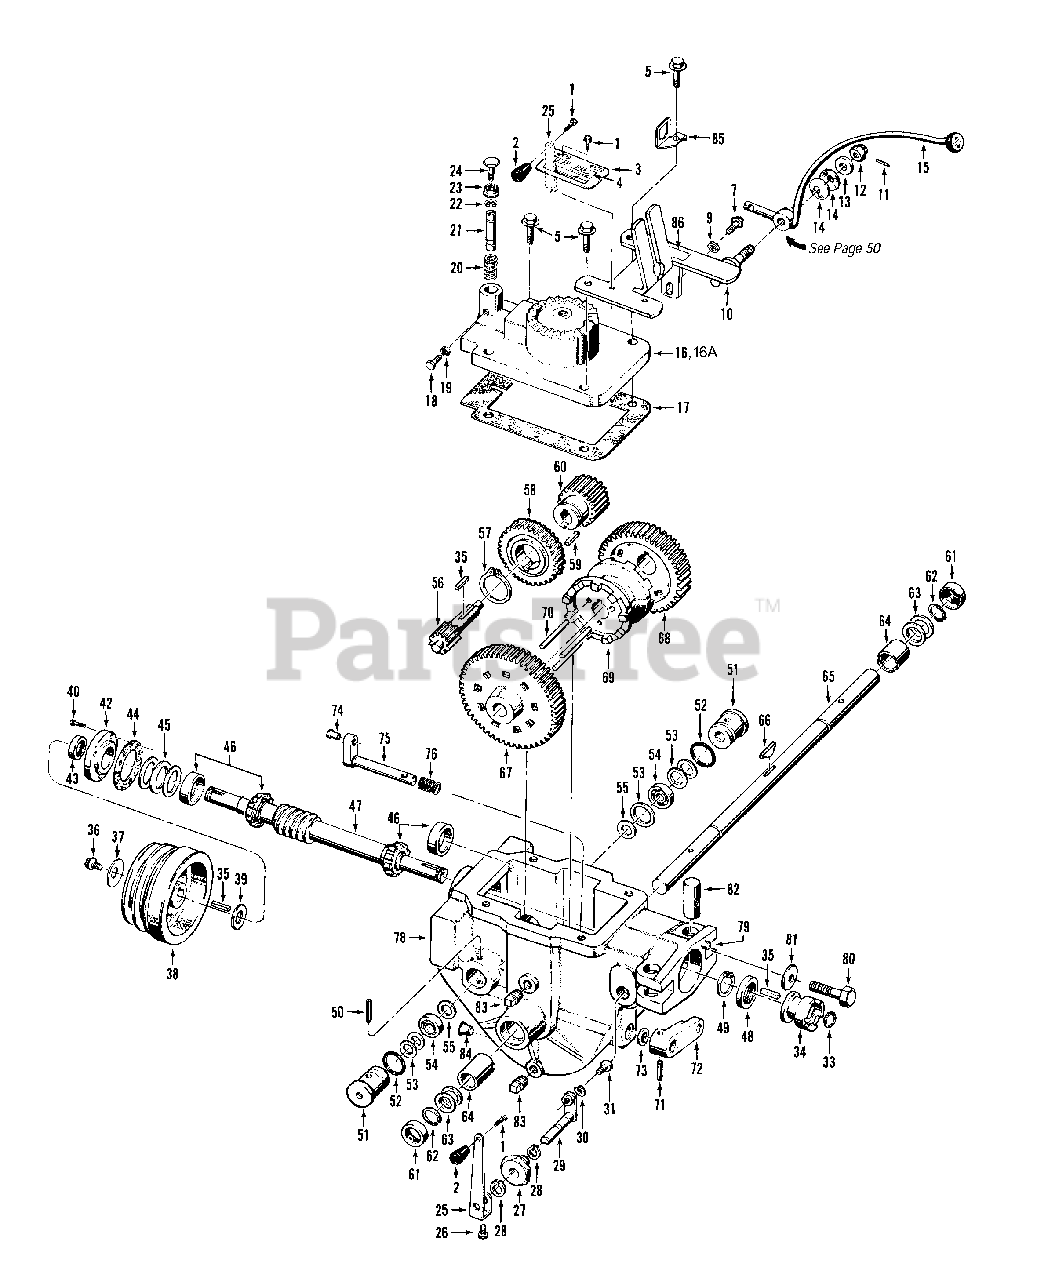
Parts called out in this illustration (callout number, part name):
1	Bolt-hex hd., #10-32 x 3/8", self-locking flange
2	Knob-tines/PTO clutch lever, tapered, plastic
3	Detent Plate-tines/PTO clutch lever
4	Decal-operating instructions, detent plate
5	Bolt-flanged hex hd., 3/8-16 x 1-1/2"
7	Bolt-flanged hex hd., 5/16-18 x 3/4", Grade 5
9	Washer-flat, 5/16", S.A.E.
10	Bracket-shift levers
11	Pin-spring, 1/8"
12	Nut-castle (slotted), 1/2"-20,
13	Washer-shoulder, 1/2"
14	Washer-disc spring
15	Lever-wheel speed shift
16	Cover-power unit transmission
16A	Cover-power unit transmission
17	Gasket-transmission cover
18	Bolt-hex hd., 5/16-18 x 1", Grade 5,
19	Nut-hex, 5/16"-18
20	Spring-neutral plunger
21	Plunger-neutral
22	Clip Ring-retains neutral plunger
23	Nut-hex, flange locknut, 3/8"-16
24	Bolt-hex hd., 3/8-16x1-1/2", threaded full length
25	Lever-eccentric, tines/PTO clutch.
26	Bolt-hex hd., 1/4-20 x 1/2"
27	Bushing-tines/PTO clutch lever eccentric shaft
28	Retaining Ring-(snap ring), external
29	Eccentric-shaft, tines/PTO clutch lever
30	Lockwasher-hi-collar, 1/4"
31	Screw-socket hd., 1/4-20 x 3/8"
33	Retaining Ring-external
34	Dog Clutch-power unit
35	Key-3/16 sq. x 1"
36	Bolt-hex hd., 5/16-24 x 3/4", self-locking flange, Grade 5
37	Washer-disc spring (concave)
38	Pulley-transmission drive, cast iron
39	Washer-flat, hardened shoulder 1-1/4"
40	Bolt-hex hd., 1/4-20 x 3/4", front bearing cap
42	Cap-front bearing
43	Seal-oil, front bearing cap
44	Gasket-front bearing cap
45	Shim-front bearing cap, .010" thick
45	Shim-as above, .030"
45	Shim-as above, .005"
45	Shim-as above, .062"
46	Bearing & Cup-tapered cone roller bearing with cup (race).
47	Shaft-main drive, power unit.
48	Seal-oil, drive shaft, rear
49	Retaining Ring-(snap ring), internal
50	Pin-roll (spirol), 1/4 x 2"
51	Plug-retaining, pinion bearing
52	O-Ring-retaining plug
53	Shim-retaining plug, 1-1/64" inner dia., .033" thick
53	Shim-same as 1132-1, .062"
53	Shim-same as 1132-1, .010"
54	Bearing-ball, pinion shaft
55	Washer-pinion shaft
56	Stem Pinion-slow speed gear & shaft
57	Ring-retaining, external
58	Worm Gear-bronze, wheel drive
59	Key-3/16" x 5/8"
60	Gear-fast speed pinion
61	Seal-oil, wheel shaft
62	Retaining ring-external
63	Shim-wheel shaft, 1-1/64" inner dia., .062" thick
63	Shim-as above, .030" thick
63	Shim-as above, .015" thick
63	Shim-as above, .010" thick
63	Shim-same as above, .005" thick
64	Bushing-bronze, wheel shaft bearing
65	Shaft-wheel, 15-5/8",
66	Key-Hi Pro, 1/4" x 1-3/4"
67	Gear-slow speed, wheel drive
68	Gear-fast speed, wheel drive
69	Dog Clutch-wheel drive
70	Pin-clutch guide, 1/4" diameter
71	Pin-roll, 3/16" x 1-1/4" (spirol)
72	Lever-eccentric, wheel speed shifting
73	Seal-oil, eccentric shaft
74	Pin-eccentric shaft, wheel speed shifting
75	Eccentric Shaft-wheel speed shifting
76	Spring-eccentric shaft
78	Housing-power unit transmission
79	Pin-alignment
80	Bolt-hex hd., 1/2-13 x 2" Grade 5
81	Washer-disc spring (concave),
82	Post-with threaded hole
83	Plug-pipe, 1/4"
84	Plug-red plastic, thread protector
85	Clip-forward interlock system plug connector
86	Decal-forward interlock wire harness
